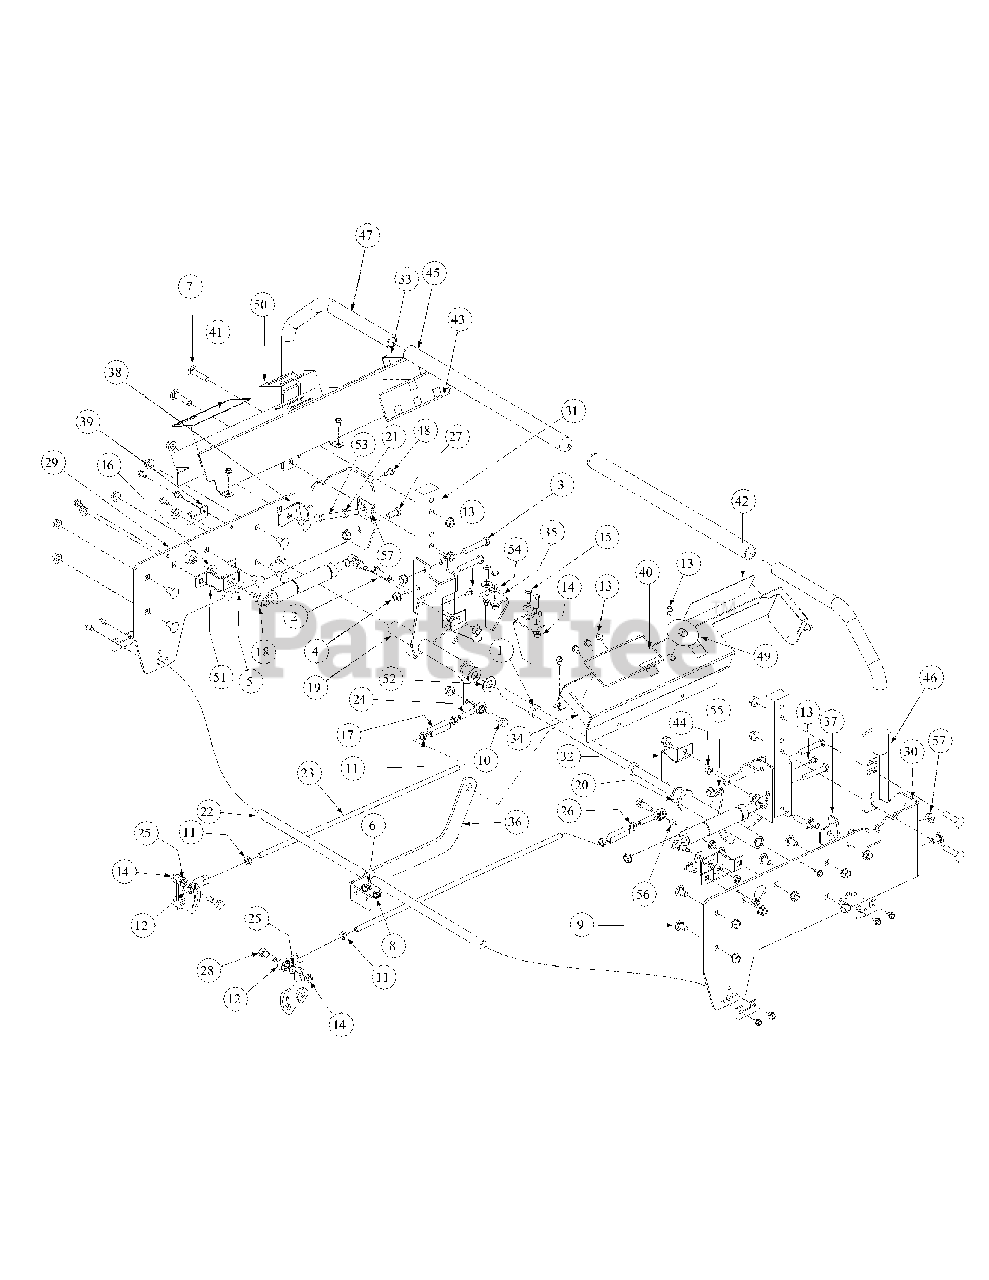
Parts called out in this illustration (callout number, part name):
1	Shaft Collar
2	HHCS, 3/8-16, 2.00
3	HHCS, 3/8-16, 2.25
4	Hex Nut, 3/8-16, Lock Flange
5	External Washer, 3/8
6	HHCS, 1/4-20, .750
7	Hex Carriage Screw, 3/8-16, 1.75
8	Lock Washer, 1/4 Zinc
9	Carriage Bolt, 3/8-16 x .75
10	Capscrew, 3/8-16 x 1-3/4
11	Hex Jam Nut, 3/8-24
12	B/Joint, 3/8-24, Right Hand Female
13	Screw, TT, 1/4-20, 0.5, Hex Index Washer
14	Nut, Lock, Hex Flange, 5/16-18
15	Hex, Cap Screw, 5/16-18 x 3/4
16	Belle Washer, .325 x .930 x .045
17	Turnbuckle
18	Cylinder Return to Neutral
19	Hub Assy, Control LH Bearing
20	Hub Assy, Control RH Bearing
21	Nut, 3/8-16, Jam
22	Shaft Control Brake Steering
23	Rod Connector 3/8 OD x 14.25
24	B/Joint, 3/8-24, Left Hand Female
25	5/16, Lock Washer
26	Nut, 3/8-24, Jam, LH Third
27	HHCS, 5/16-18 x 1.0
28	Screw, Shoulder Control Rod
29	Side Panel, Control, Left
30	Side Panel, Control, Right
31	Mounting Handle
32	Lever, Safety Switch
33	Control Panel, LH
34	Control Panel, RH
35	Switch Mounting Bracket, Lapbar
36	Link Mounting Control Shaft, Bracket
39	Holder Shaft, Park Brake
40	Decal , Right Hand Console
41	Decal, Left Hand Console
42	Decal Right Hand Control
43	Decal, Left Hand Control
44	Nut, Hex, Center Lock, M8
45	Grip, 1.0
46	Lapbar, Weldment, Right Handle
47	Lapbar, Weldment, Left Handle
48	Screw, TT, 1/4-20, 0.75, Hex Index Washer
49	Label, Ingnition, 2.5 Diameter
50	Label, Control, Throttle and Choke
51	Bracket Assembly, Mount Dampener
52	Flat Washer, 5/8 Nylon
53	HHCS, 3/8-16, 3.00
54	Flat Washer, 5/16
55	Grease Fitting, 90°.
56	Spacer, .385 ID x .625 OD x >50 Lg
57	U-Nut, 3/8-16, .75
